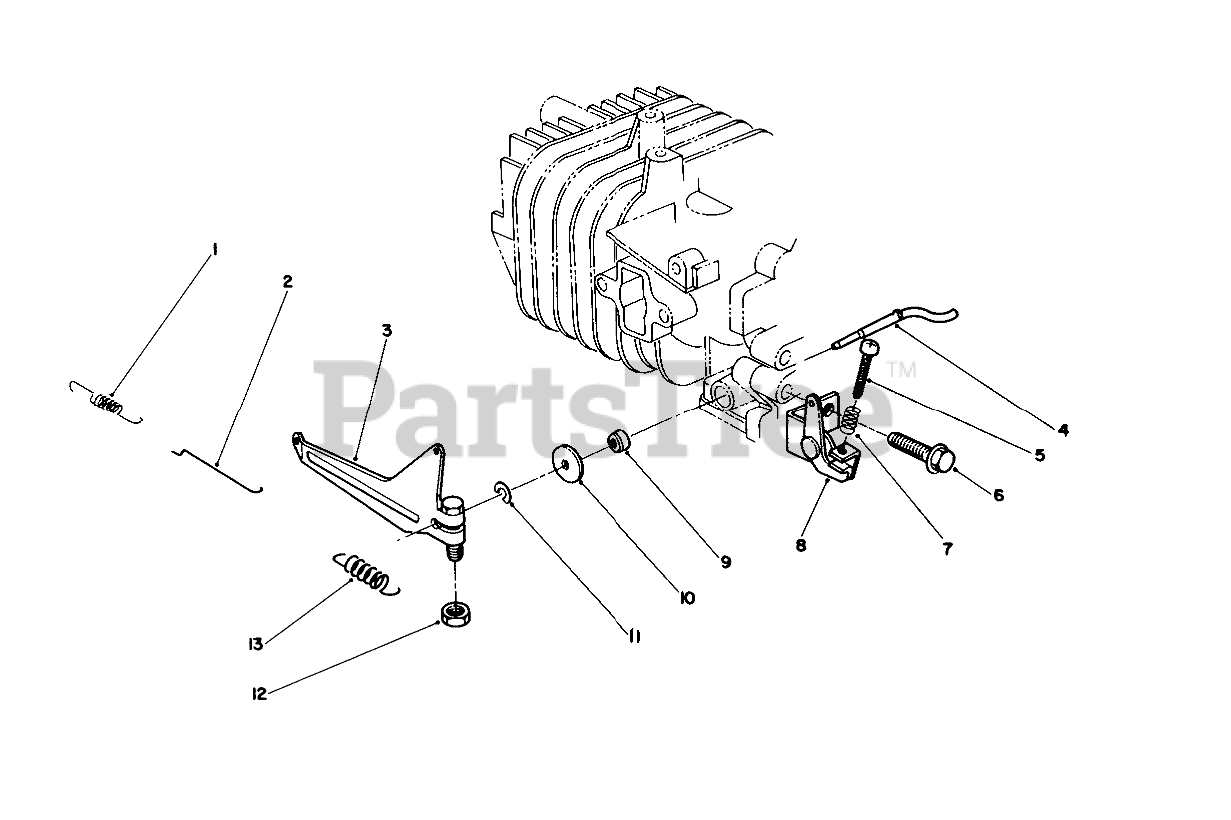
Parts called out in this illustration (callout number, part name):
1	CARB SPRING
2	CARB ROD
3	GOV ARM
4	SHAFT
5	SCREW
7	SPRING
8	GOV SPR BRKT
9	SEAL-OIL
10	WASHER
11	E-RING
13	GOV SPRING
